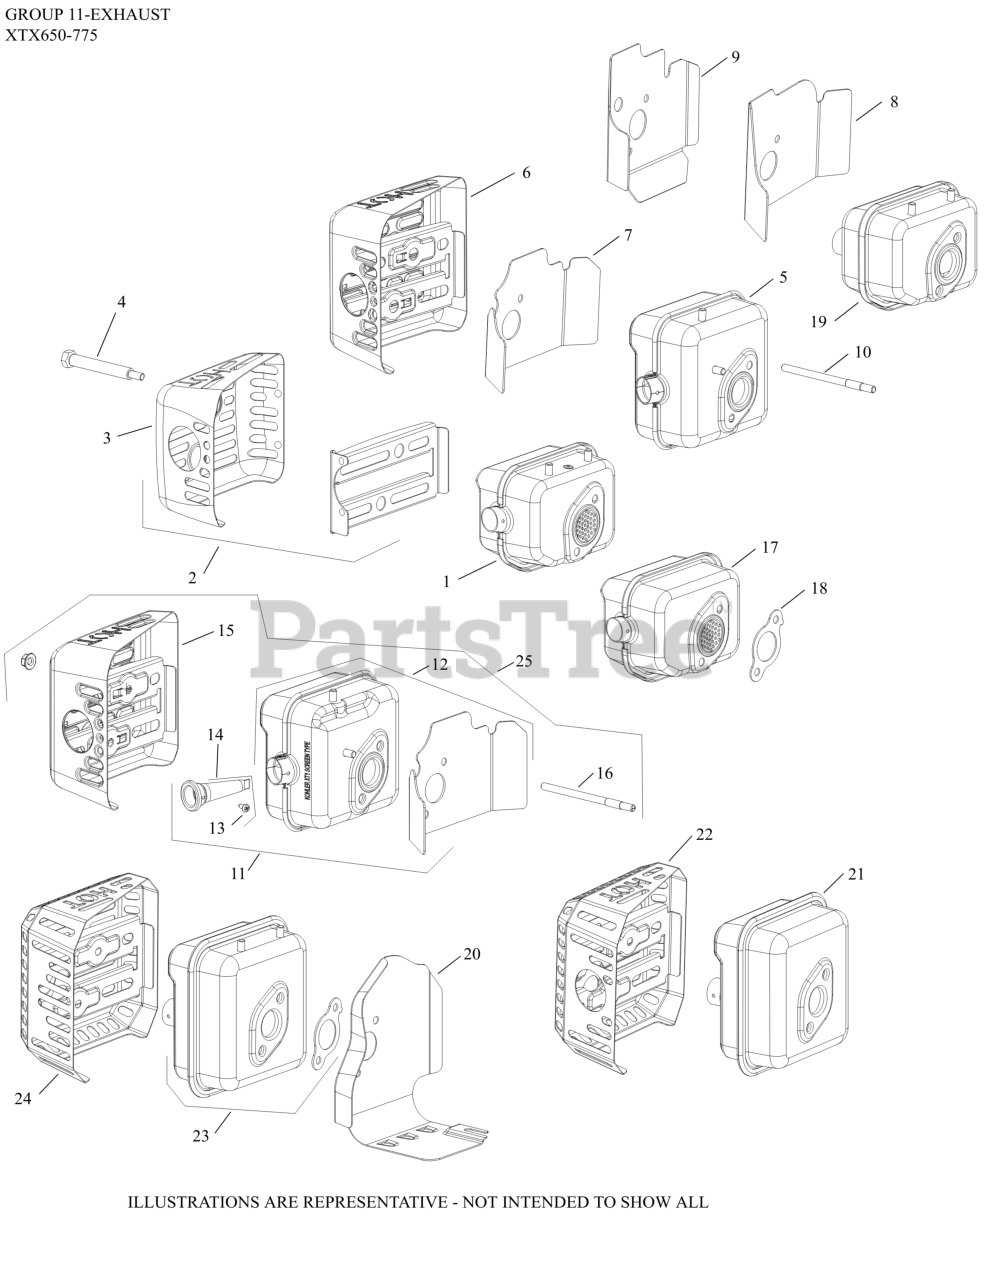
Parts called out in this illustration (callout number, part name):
7	GASKET, MUFFLER (HEAT DEFLECTOR)
12	KIT, MUFFLER
15	GUARD, MUFFLER ASSEMBLY
16	STUD, EXHAUST (M6)
